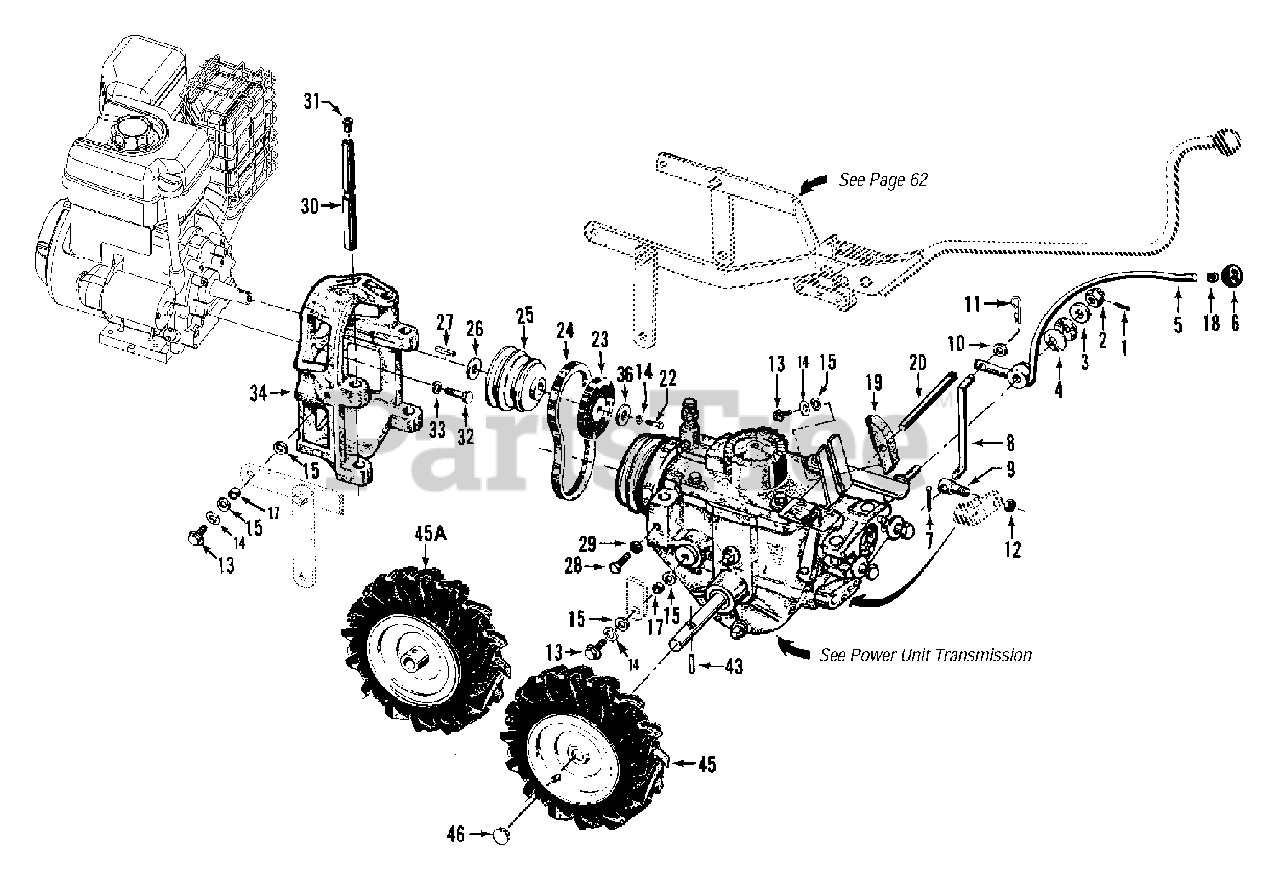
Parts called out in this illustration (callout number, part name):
1	Pin-spring, 1/8"
2	Nut-castle (slotted), 1/2"-20
3	Washer-shoulder, 1/2"
4	Washer-disc spring
5	Lever-wheel speed shift
6	Knob-wheel speed shift lever
7	Pin-cotter, 3/32" x 1"
8	Connecting rod, wheel speed -shift lever
9	Swivel-connecting rod
10	Washer-flat, 5/16", S.A.E.
11	Pin-hair cotter
12	Locknut-hex hd., 5/16"-18
13	Bolt-flanged hex hd., 3/8-16 x 1"
14	Lockwasher-spring lock, 3/8"
15	Washer-flat, 3/8", S.A.E.
17	Bushing-spacer, 19/64" (.300"lg.)
18	Ring-retaining (tolerance ring)
19	Block- belt adjustment, 3-7/8"
20	Rod- belt adjust., 7" with measuring gauge
21	Decal- engine stabilization
22	Bolt-hex hd., 3/8-24 x 1-1/2"
23	Disc-reverse
24	Belt-forward drive
25	Pulley-engine power take off
26	Shim-engine pulley, 1/16"
26	Shim-as above, 1/32"
27	Key-engine pulley, 3/16"sq. x 2-1/2"
28	Bolt-hex hd., 5/16-18 x 1", Grade 5
29	Nut, hex, 5/16-18
30	Bar-engine mounting
31	Plug-thread protector, red plastic
32	Bolt-hex hd., 5/16-24 x 1-1/8"
33	Lockwasher-spring lock, 5/16"
34	Mount- engine to tiller
36	Washer, flat, .406 x 1.0 x .105
43	Pin- roll, 5/16" x 1-1/2"
45	Wheel & Tire Assy
45A	Wheel & Tire Assy
46	Cap-wheel hub
